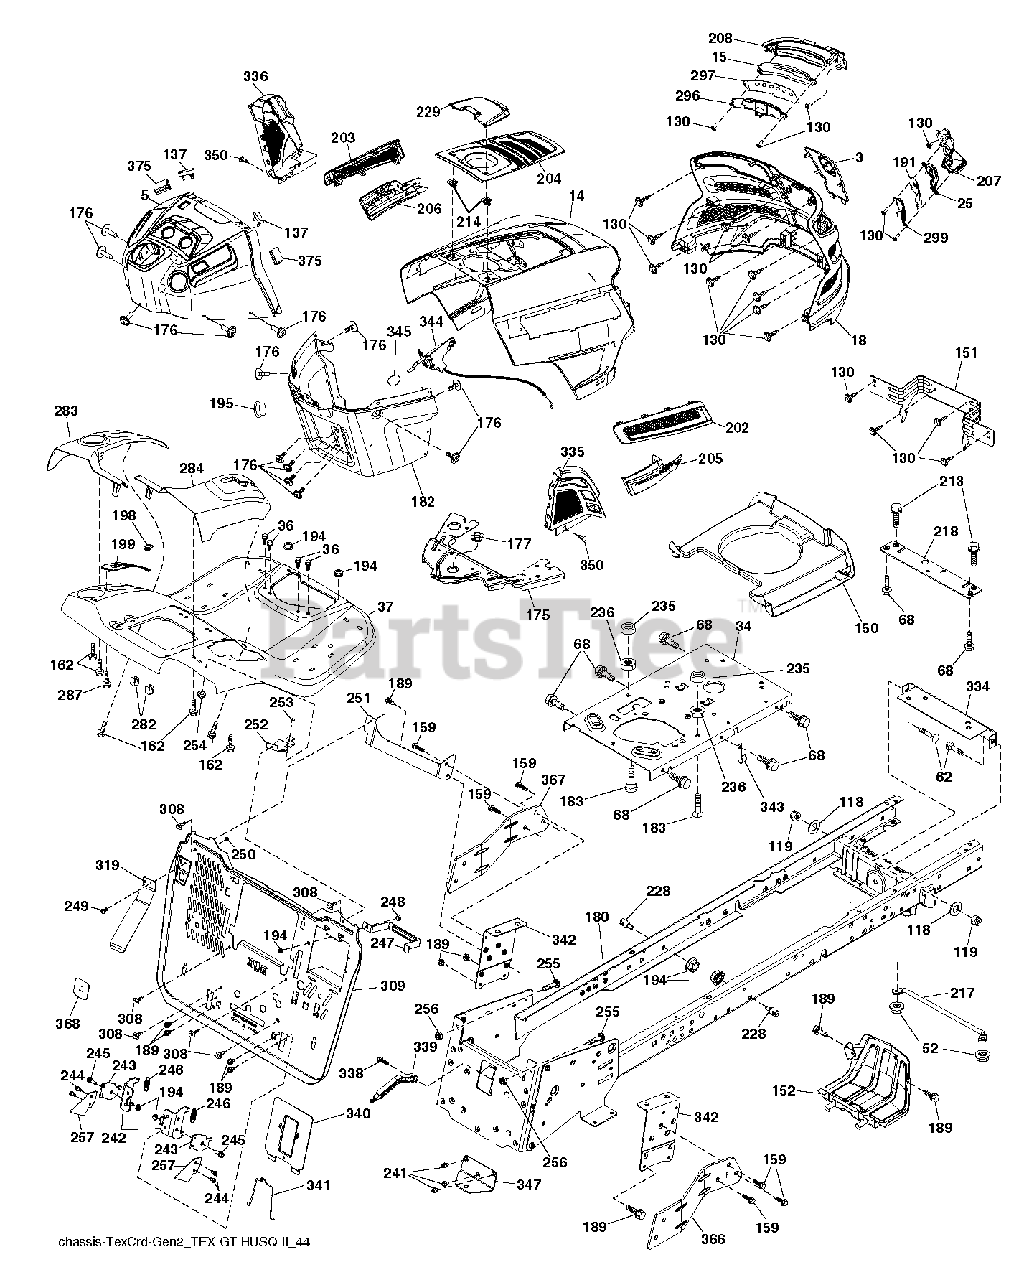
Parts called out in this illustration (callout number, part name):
3	APPLIQUE.SUBASM.GT.HUSQ.II
5	DASH.UPP.GT2.DUAL.RD.PT
14	HOOD.ASM.HUSQVARNA.GT.TEX.ORAN
15	LED LIGHT.LH
18	GRILLE SUBASM.GT.II.LOW.HDLGHT
25	LENS.RH
34	PLATE.ENGINE.10GA.CRD.GENII
36	SCREW 5/16"
37	FENDER.TEX.SRD.CRD.BASE
52	LOCKNUT
62	BOLT D
68	SCREW LT
118	WASHER
130	SCREW.#10 X 0.750.BOS
137	BUMPER DASH
150	AIR DUCT.GTV2(1.66"RING HEIGHT
151	BRACKET.PIVOT.HOOD.GT.HUSQ.II
152	SHIELD.BROWNING.PNT.GT.V2
159	SCREW, 3/8-16X3/4
162	SCREW.HI-LO.CONSOLE
175	PLATE.CROSSMEMBER.HUSQ
176	SCREW.#10-24X5/8.RN.QU
177	BUSHING STEERING
180	WELDMENT.CHASSIS.TEX.CRD.GEN.2
182	DASH DASH LOWER
183	BOLT.5/16-18X1-1/4 FULL THD
189	SCREW
191	INSERT INFLECT.RH
194	NUT LOCK HEX FLANGE 5/16-18
195	PLUG.HOLE.DASH.LOWER.12V.BLK
198	INDICATOR.DECK.LIFT.RED
199	PLATE DECK LIFT
202	VENT.SIDE.RH.GT.HUSQ.II.
203	VENT.SIDE.LH.GT.HUSQ.II.498
204	VENT.TOP.EXTERNAL.FILL.GT2.GRE
205	SIDE.TRIM.RH.GT.HUSQ.II
206	SIDE.TRIM.LH.GT.HUSQ.II.GRAY
207	BEZEL GT2 LED RH W/ LOWER.ATT
208	BEZEL GT2 LED LH W/ LOWER ATT
213	BOLT
214	CLIP.RETAINER.TINNER.
217	ROD.PIVOT.HOOD
218	X-PIECE.HOOD.STOP.NON/
228	STUD.FASTNER.W/ANTI-ROTATE
229	LID.EXT.FILL.GT.HUSQ2.BLACK
235	SPACER FENDER
236	NUT.CENTERLOCK.5/16-
241	SCREW 5/16-18X1
242	LATCH.BRACKET.TCRD.GEN 2.5.BAG
243	ARM.PIVOTING.TCRD.GEN2.5.BAGGE
244	SCREW
245	BOLT, SHOULDER
246	SPRING.TCRD.GEN2.5.BAGGER.EXT
247	STRAP.BATTERY.TCRD.GE
248	BOLT
249	SCREW.BUTTONHD.10-24X1/2.(2 2)
250	NUT 10-24 NYLOC
251	BRKT.TOPSPPRT.BCKPLT.
252	BRKT.TOPSPPRT.BCKPLT.RH.CRD2.5
253	BOLT
254	NUT T
255	BOLT.CROSSDRILLED.381
256	Hex Nut, 3/8-16
257	LATCH.BAGGER.TEXCRD2.5
282	CLIP.RETAINER.CONSOLE.LT.HUSQ
283	CONSOLE.DECKLIFT.CRDII.498
284	CONSOLE.PEDAL.HYDRO
287	SCREW 1/4X20
296	LED LIGHT.LH
297	INSERT REFECT LH
299	LED LIGHT.RH
308	BOLT, 5/16-18 X 1 3/4
309	BACKPLATE.TEXCRD2.5.B
319	LEVER.BAG.CRDII.ANTIROTATION
334	BRACKET.ENGINE
335	COVER.LOWER.DASH.RH.BLACK
336	COVER-LH.LOWER.DASH.GT2.BLACK
338	BOLT BOLT SHOULDER
339	LEVER LEVER BAGGER
340	BATTERY.DOOR.TCRD.GEN
341	LATCH.BATTERY.DOOR.TC
342	SUPPORT SUPPORT FENDER
343	CLIP CLIP
344	CONTROL.EZ.MULCH.TEX/CRD
345	RP KNOB.OVAL.TAPERED.3/8-16BLK
347	HITCH HITCH TOW TEX CRD GEN 2
350	CLIP.X-MAS.TREE
366	BRACKET.RH.FRONT.BAGGER.BLACK
367	BRACKET.LH.FRONT.BAGGER.BLACK
368	FULL.LEVER.BAGGER.TEX.CRD
375	BUMPER CLIP-ON. DASH 1"
